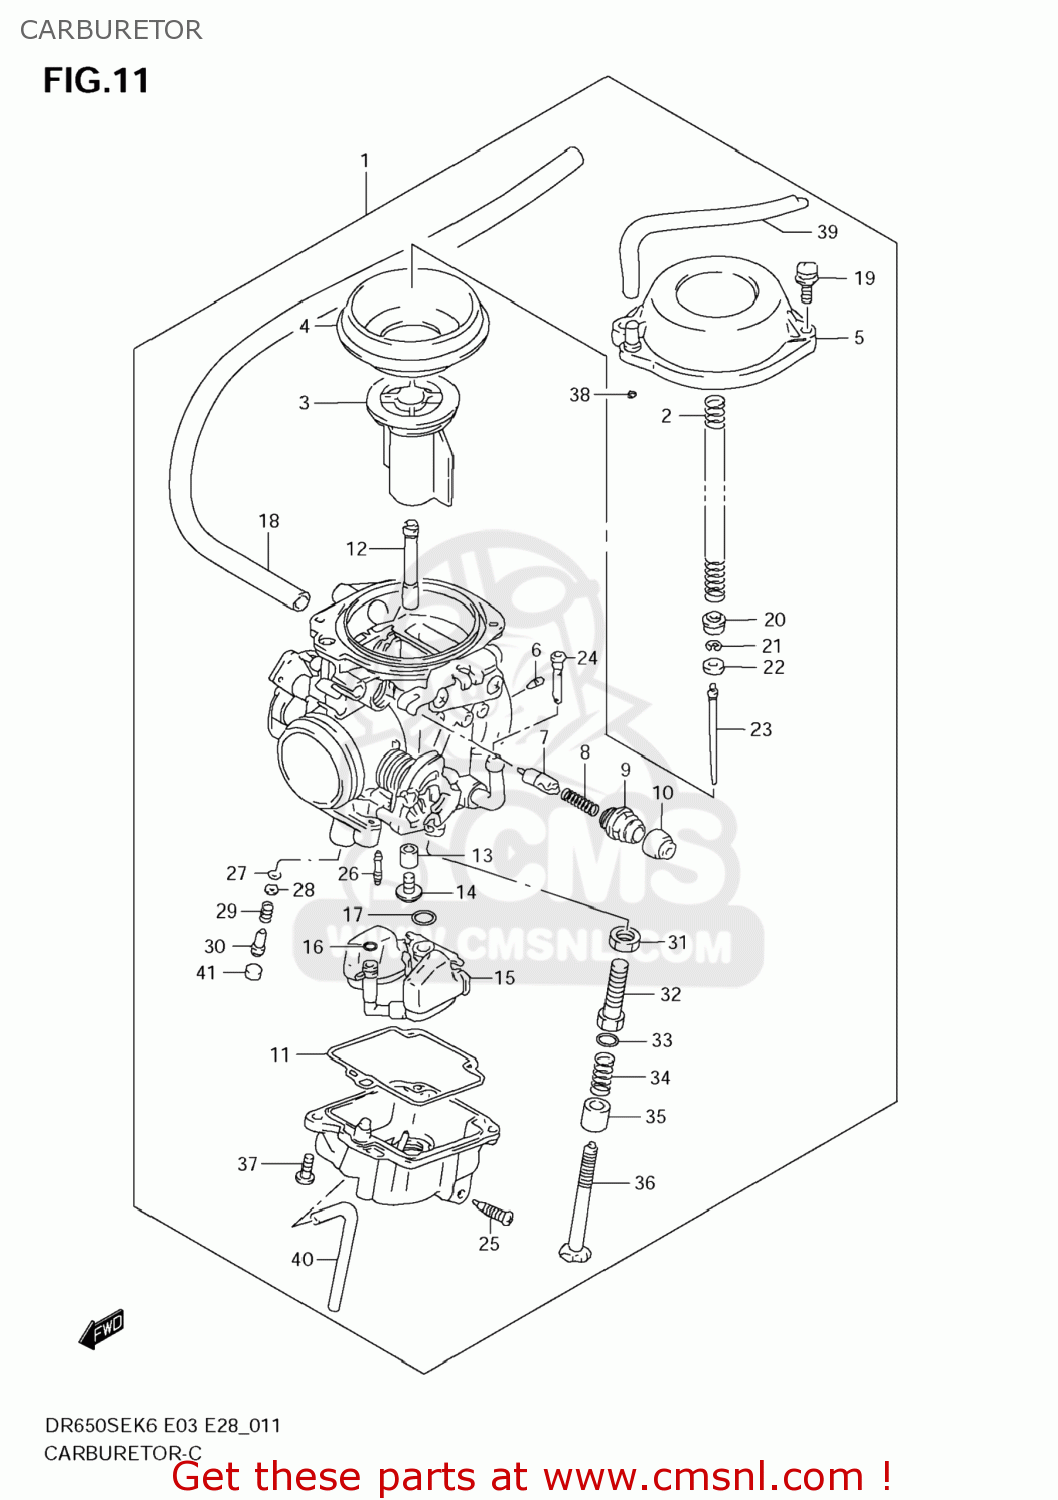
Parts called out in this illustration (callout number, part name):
1	CARBURETOR ASSY
2	SPRING
3	VALVE,PISTON
4	DIAPHRAGM
5	COVER,DIAPHRAGM
6	JET,AIR(1.0)
7	PLUNGER
8	SPRING
9	HOLDER,GUIDE
10	CAP
11	GASKET,FLOAT CHAMBER (NAS)
12	JET,NEEDLE(Y-5M)
13	RING
14	JET,MAIN(140)
15	FLOAT/NEEDLE VALVE ASSY
16	O RING
17	O RING,NEEDLE VALVE SEAT
18	HOSE(6.5X10.5X275)
19	SCREW
20	RING
21	CLIP,NEEDLE
22	RING
23	NEEDLE,JET(6F23)
24	FILTER
25	SCREW,DRAIN
26	JET,PILOT(42.5)
27	O RING,PILOT AIR SCREW
28	WASHER
29	SPRING
30	SCREW,PILOT
31	NUT
32	ADJUSTER
33	WASHER,STARTER SHAFT
34	SPRING
35	RING
36	ADJUSTER
37	SCREW(5X14)
38	O RING
39	HOSE(4.5X8.5X600)
40	HOSE(3X5X450)
41	PLUG
